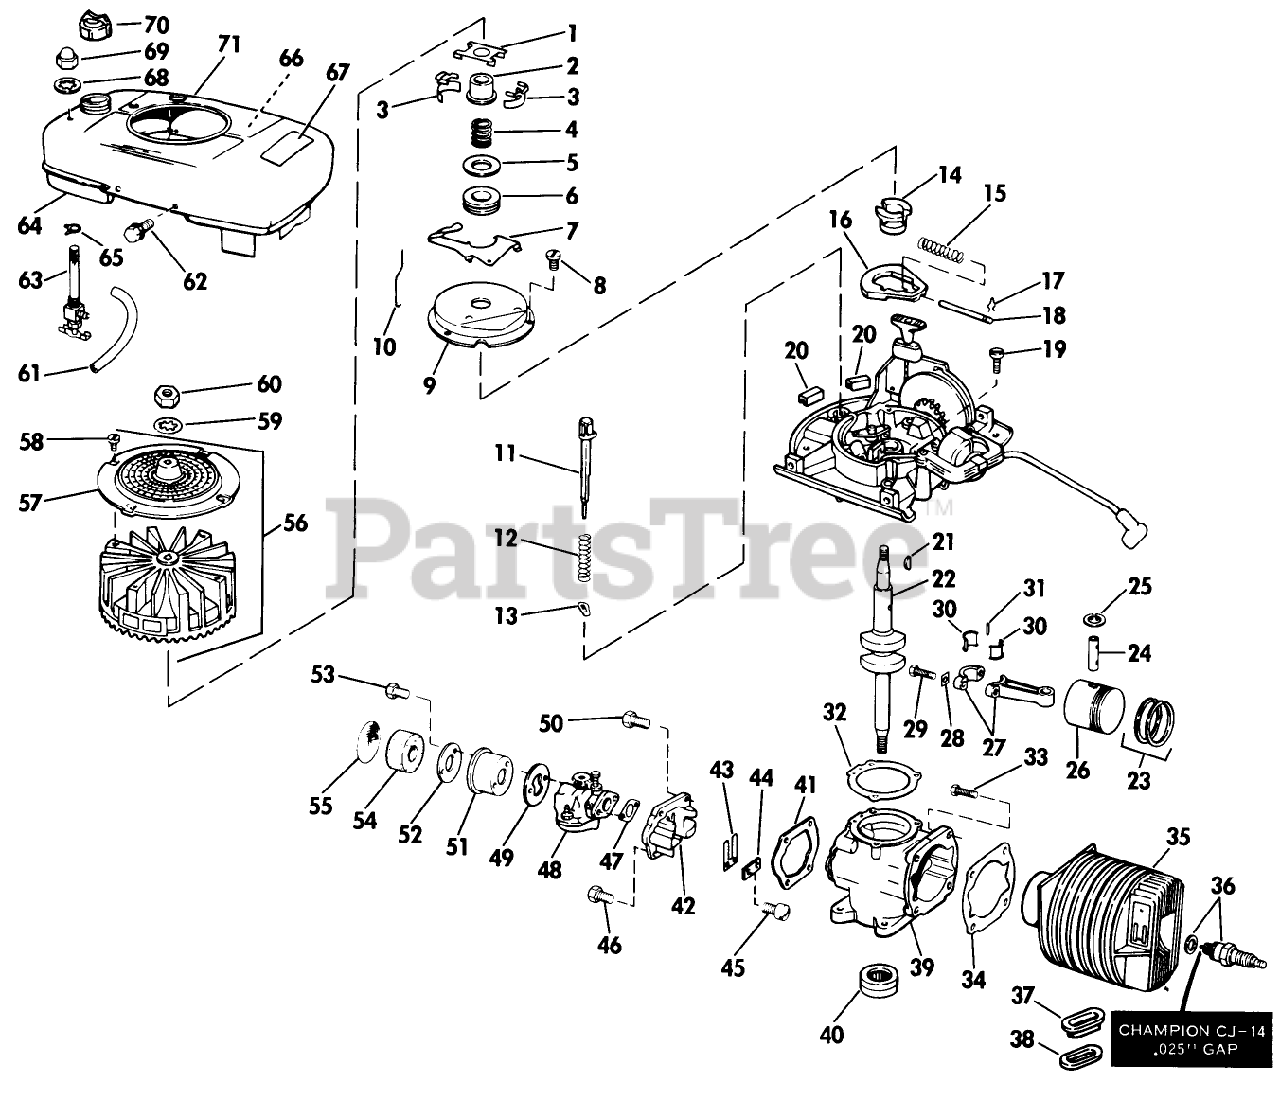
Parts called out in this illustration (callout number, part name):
2	COLLAR S
6	THRUST COLLAR S
7	LEVER-GOVERNOR S
8	SCREW S
9	DUST COVER S
12	SPRING S
14	SPARK ADV. S
15	SPARK ADV. SPRING S
16	FLYWEIGHT S
17	SPARK ADJ. SPRING
18	PIN,SPARK ADV. S
25	RING-RETAINING
30	LINER ASM
32	GASKET S
34	GASKET S
36	Spark Plug and Gasket
38	GASKET S
42	REED PLATE AY. S
44	PLATE-BACKUP, REED
46	SCREW S
47	GASKET S
49	GASKET S
50	SCREW S
52	BACK-UP PLATE
54	ELEMENT
56	Flywheel Screen Assy.
58	SCREW F
62	SCREW S
63	VALVE&SCREEN SM
65	CLAMP - HOSE S
69	PALNUT S
